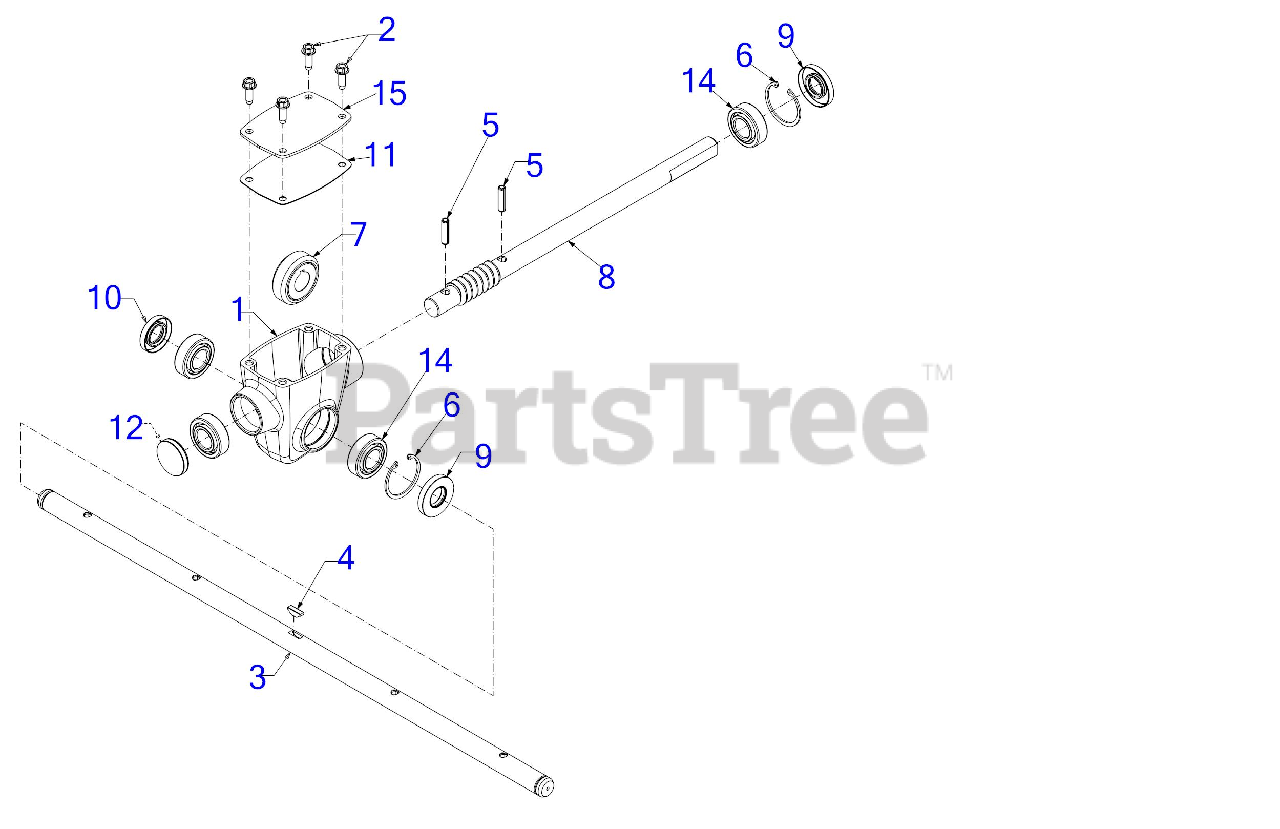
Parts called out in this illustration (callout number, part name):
1	AUGER GEARBOX HOUSING
2	SCREW 1/4-20 x .750
3	26" AUGER AXLE
4	KEY 3/16 x 5/8 H
7	WORM GEAR 20T
8	WORM SHAFT
11	GEARBOX COVER GASKET
12	GEARBOX PLUG
14	BALL BEARING
15	GEARBOX COVER
